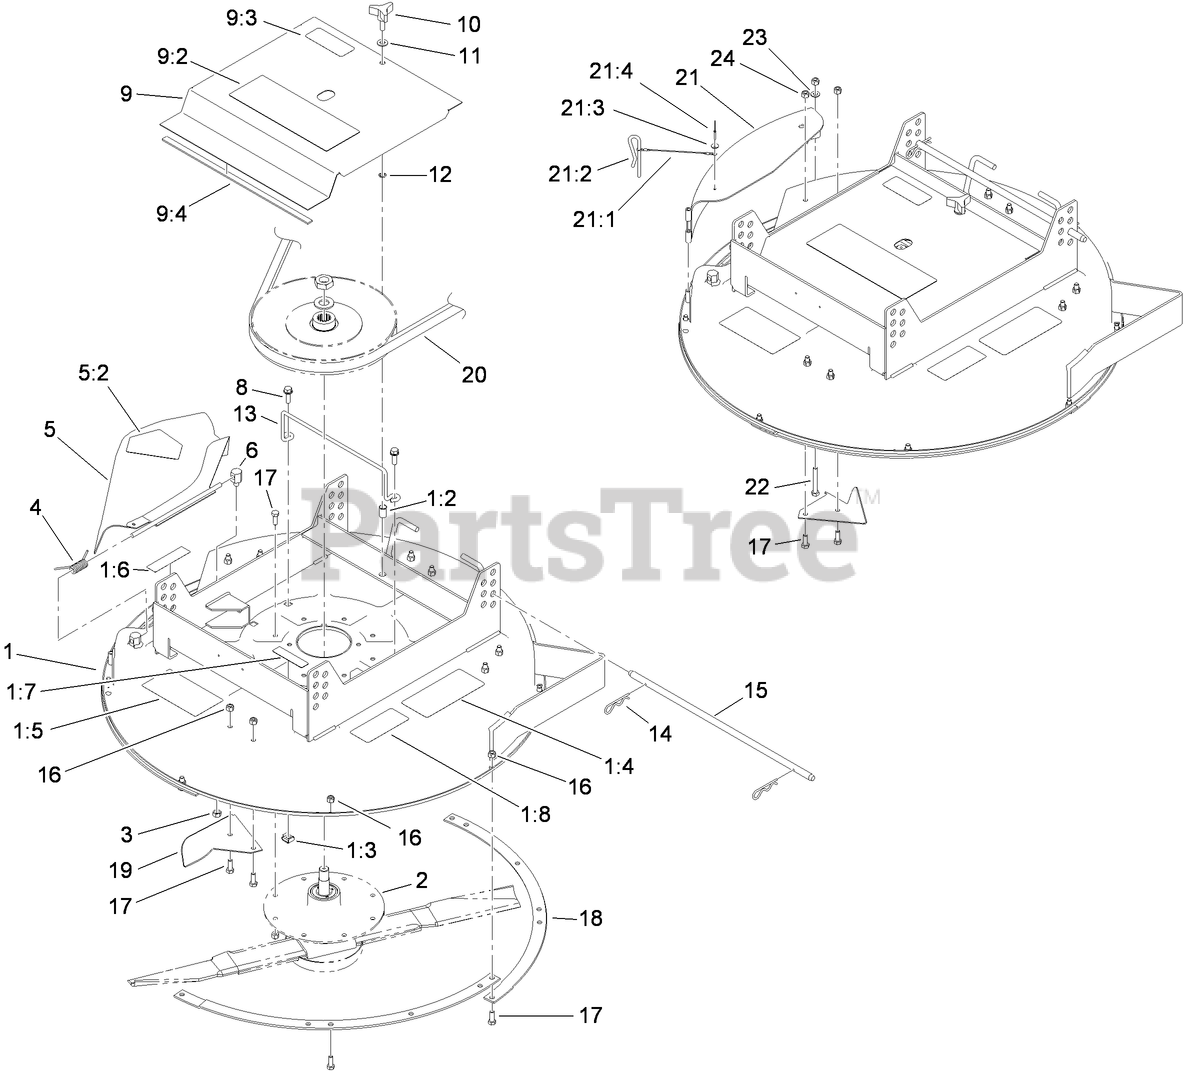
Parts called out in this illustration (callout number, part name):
1	32 INCH DECK ASM
1:2	INSERT-NUT
1:3	NUT-RETAINER
1:4	DECAL-HOC
1:5	DECAL-DANGER, THROWN OBJECT
1:6	DECAL-DANGER
1:7	DECAL-DANGER
1:8	DECAL-TORQUE
2	SPINDLE ASM
3	NUT-LOCK, SIDE
4	SPRING
5	DEFLECTOR ASM
5:2	DECAL-DANGER
6	POST-PIVOT
8	SCREW-HHF
9	BELT COVER
9:3	DECAL-HOT
9:4	STRIP-MAGNETIC
11	WASHER-FLAT
12	RING-RETAINING
13	GUIDE-BELT
14	PIN-HAIR
15	ROD-SUPPORT
16	NUT-LOCK, NI
17	SCREW-HH
18	RING-RECYCLER
20	V-BELT
21	MULCHER COVER ASM
21:1	LANYARD
21:2	PIN-LOCKING, CHUTE
21:3	WASHER-PLAIN
21:4	RIVET-BLIND
22	SCREW-HH
23	WASHER-PLAIN
24	NUT-LOCK, NI
